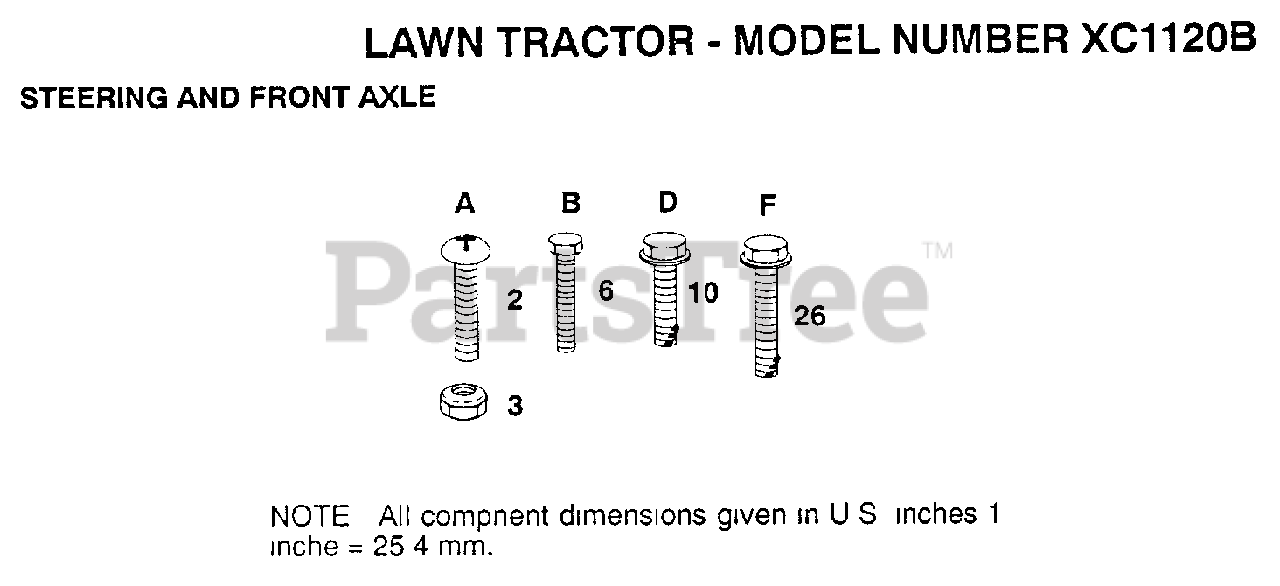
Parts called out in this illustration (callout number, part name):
2	SCREW
6	SCREW LT
10	SCREW LT
26	SCREW
